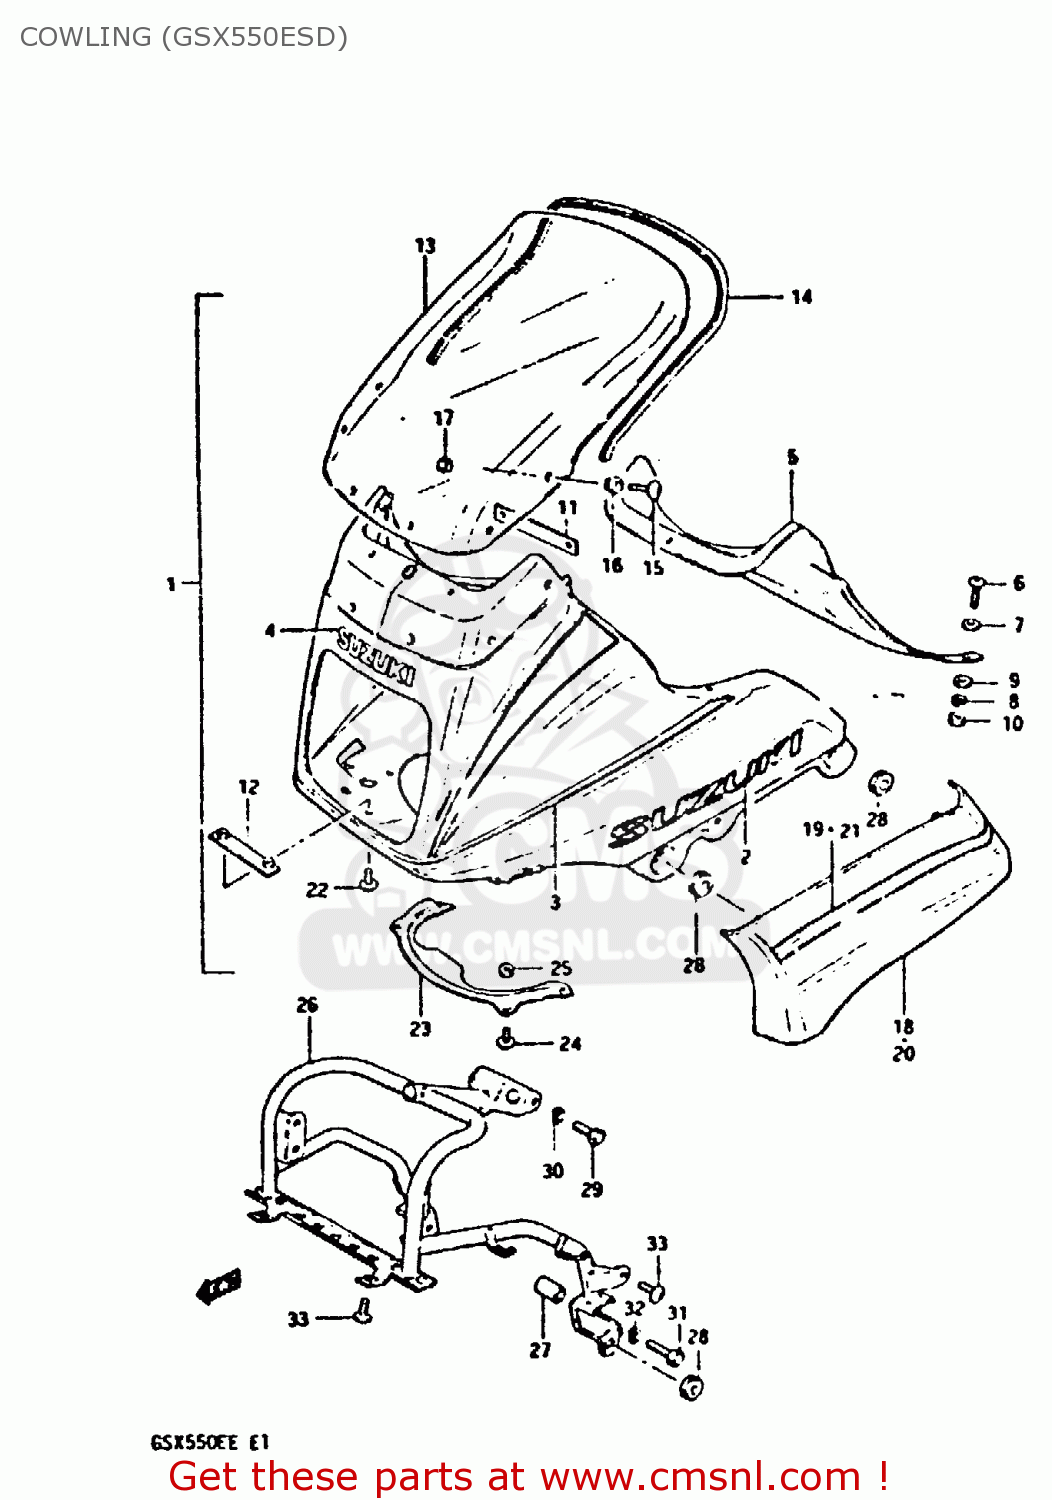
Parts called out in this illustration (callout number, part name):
1	COWLING ASSY
2	EMBLEM,FUEL TANK
3	TAPE SET
4	EMBLEM,HEADLAMP
5	PANEL,COWLING,UPPER
6	SCREW
7	WASHER,5MM
8	WASHER,LOCK
9	WASHER,5MM
10	NUT ,5MM
11	BRACKET,COWLING,UPPER
12	BRACKET,COWLING,LOWER
13	WINDOW,COWLING
14	MOLDING,LOWER
15	SCREW
16	CUSHION
17	NUT
18	COVER, RH
19	TAPE SIDE RH
20	COVER, LH
21	TAPE SIDE LH
22	SCREW
23	COVER, LOWER
24	SCREW
25	NUT 5MM
26	BRACE,COWLING
27	SPACER (8.2X12.5X23.5)
28	CUSHION
29	BOLT
30	LOCK WASHER
31	BOLT
32	LOCK WASHER
33	SCREW 6X12
